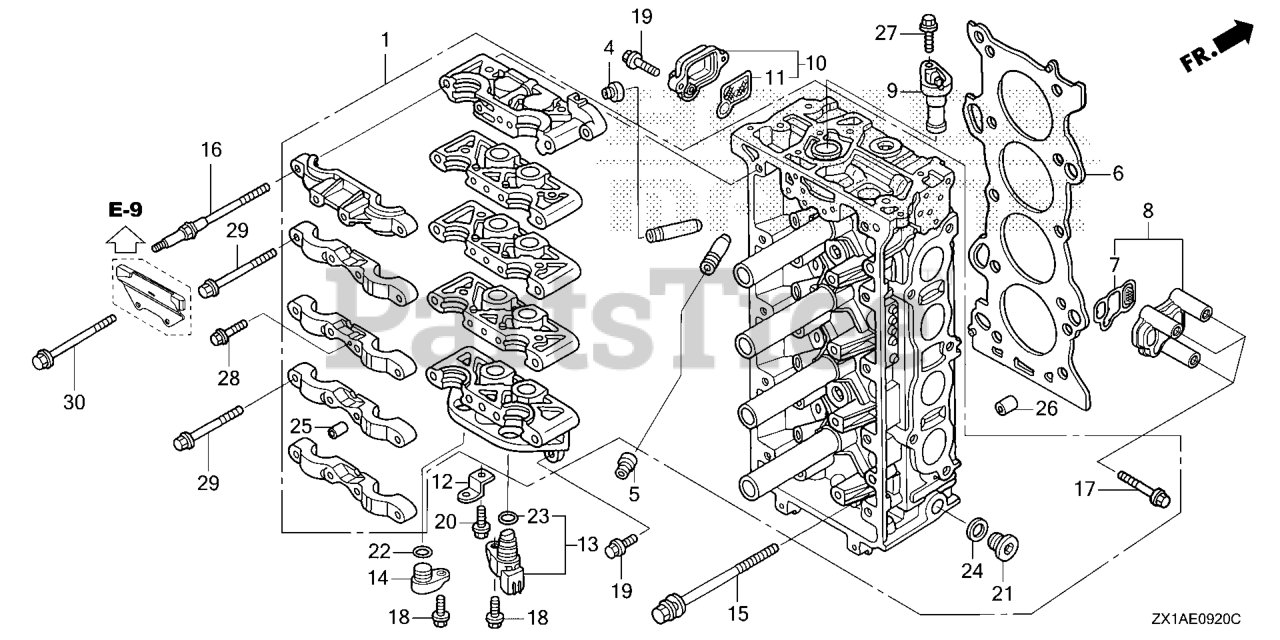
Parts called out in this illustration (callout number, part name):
1	CYLINDER HEAD KIT *N
1	CYLINDER HEAD KIT *NH8* (DARK GRAY)
2	GUIDE, VALVE (OVER SIZE)
3	GUIDE, EX. VALVE (OVER SIZE)
4	SEAL A, VALVE STEM (NOK)
5	SEAL B, VALVE STEM (NOK)
6	GASKET, CYLINDER HEAD
7	FILTER ASSY., SPOOL VALVE
8	COVER ASSY., OIL PASSAGE
9	PLUG, VTC HOLE
10	STRAINER ASSY., VTC *NH8* (DARK GRAY)
11	FILTER ASSY., VTC
12	BRACKET F, CLIP
13	SENSOR ASSY., TDC
14	PLUG, TDC HOLE
15	BOLT-WASHER (11X155)
16	BOLT A, HEAD COVER
17	BOLT, FLANGE (6X52)
18	BOLT, FLANGE (6X16)
19	BOLT, FLANGE (6X20)
20	BOLT, FLANGE (6X14)
21	BOLT, SEALING (20MM)
22	O-RING (15X1.9)
23	O-RING (15X1.9)
24	WASHER, DRAIN PLUG (20MM)
25	PIN A, DOWEL (10X16)
26	PIN A, DOWEL (14X20)
27	BOLT, FLANGE (6X20)
28	BOLT, FLANGE (6X32)
29	BOLT, FLANGE (8X90)
30	BOLT, FLANGE (8X110)
